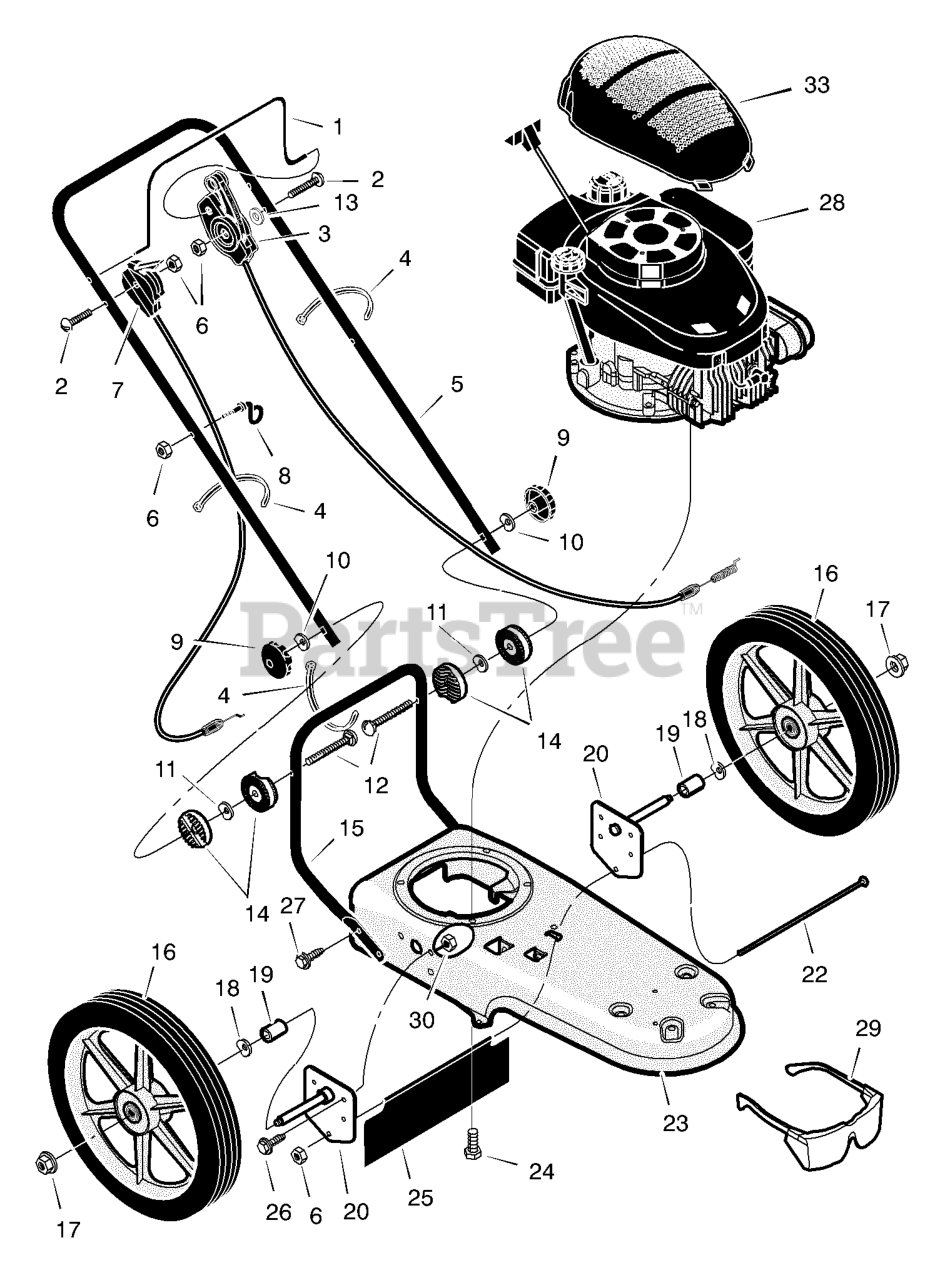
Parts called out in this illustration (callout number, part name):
1	Lever, Stop
3	Cable, Control Latching
4	Tie, Cable
6	Nut
7	Control, Throttle
8	Guide, Rope
9	Knob, Handlebar
11	Washer, Spring
14	Pivot, Handlebar
15	Handlebar, Lower
16	Wheel & Tire
17	Nut, Axle
18	Washer, Spring
20	Assembly, Axle & Bracket
22	Bolt, Carriage
25	Shield, Trailing
26	Bolt
28	Engine
29	Glasses, Safety
30	Nut
33	Shroud, Engine
